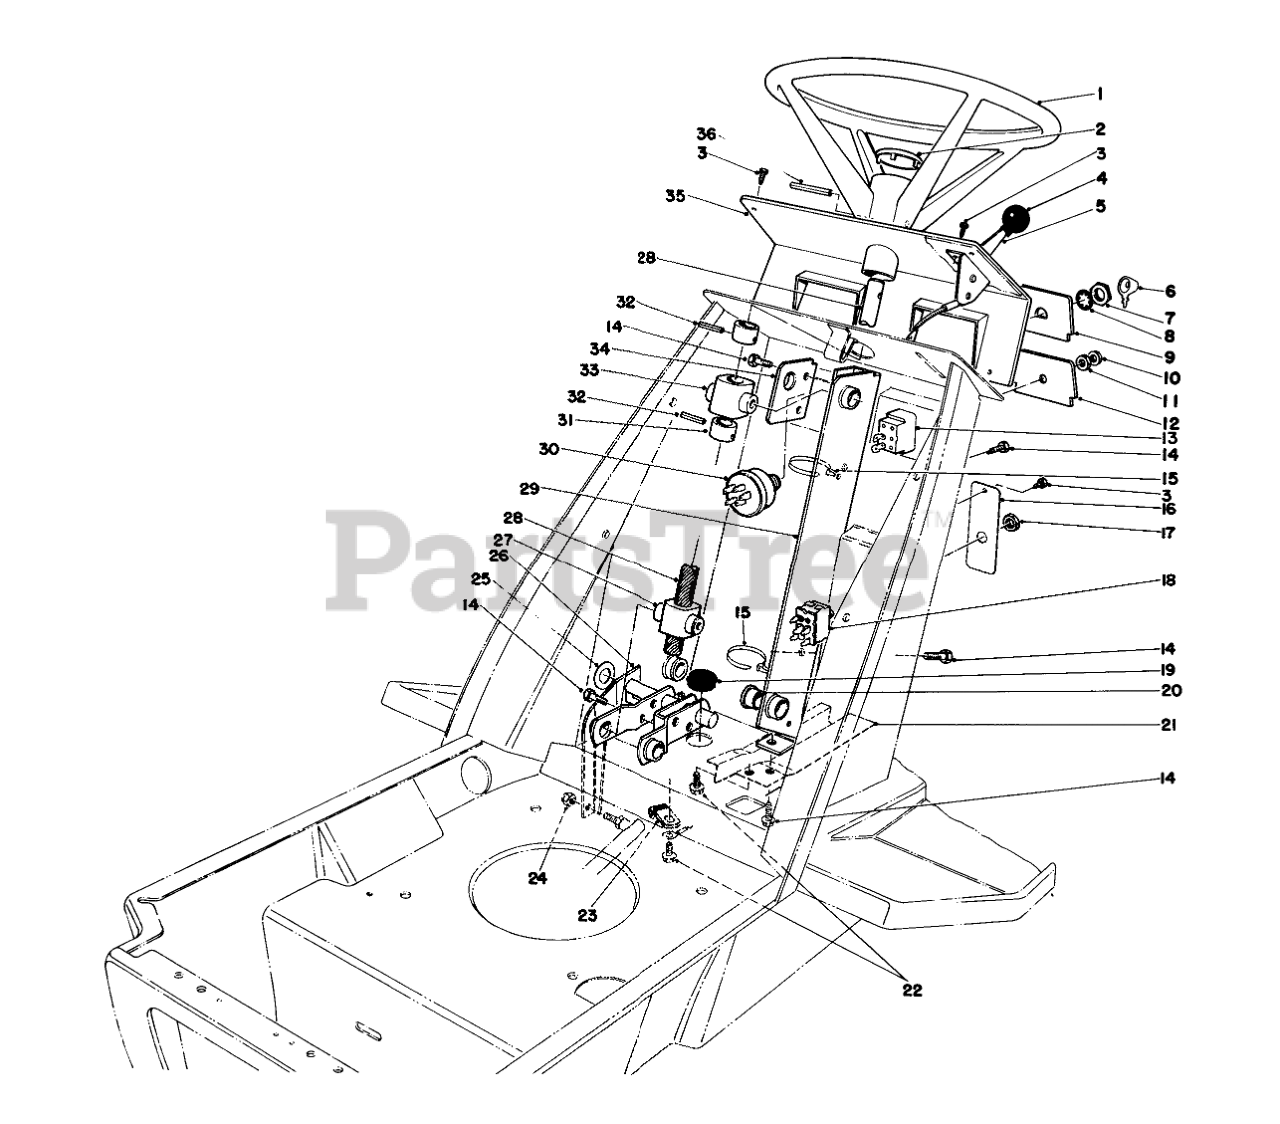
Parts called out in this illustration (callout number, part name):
1	Steering Wheel Assembly (Incl. Ref. #2)
2	Cap-Steering Wheel
3	SCREW-HWHTF
4	KNOB-CONTROL
5	Throttle Control (Incl. Ref. #4)
6	Key
7	NUT-HH
8	WASHER-TOOTH, INTERNAL
9	DASH PANEL INSERT
10	NUT-BULB
11	NUT-LOCK
12	DASH PANEL INSERT
13	Light Switch (Model #57360)(Incl. Ref. #10 & 11)
14	SCREW-HWHTF
15	Cable Tie (Incl. w/Wire Harness)
16	CLUTCH PLT SWITCH
17	NUT
18	Switch-Clutch (Incl. Ref. #17)
19	Grommet (Incl. w/Wire Harness)
20	BEARING-FLANGE
21	WIRE HARNESS SHLD B
22	SCREW-HWH
23	CLIP-FUEL LINE
24	NUT-HEX
25	WASHER
26	STEERING LINK WA BO
27	FOLLOWER STEER SHAFT
28	STEERING SHAFT
29	STRG BRKT B
30	Ignition Switch (Incl. Ref. #6-8)
31	STRG SHAFT COLLAR
32	PIN-SPRING
33	BRG STEERING SHAFT
34	STRG BRG SUPPORT
35	DASH PANEL
36	PIN-ROLL
